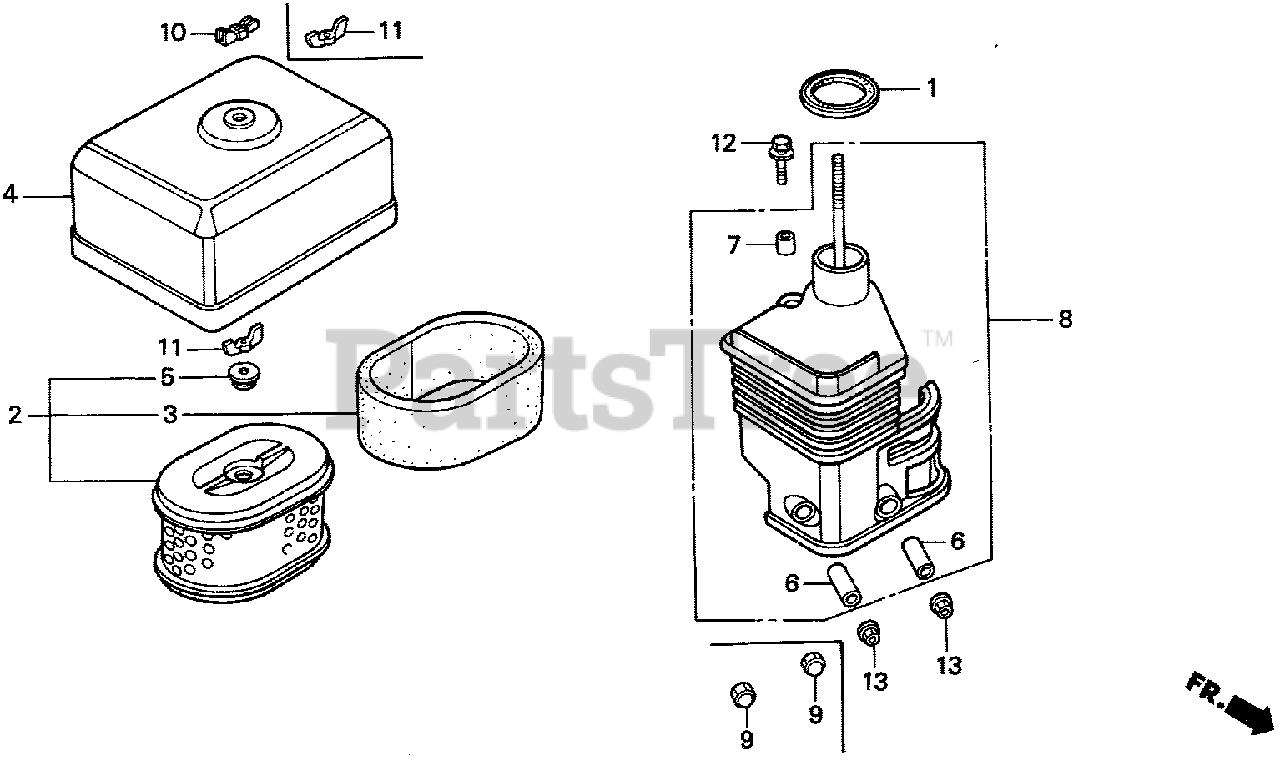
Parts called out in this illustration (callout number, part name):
1	GASKET, ELBOW
2	ELEMENT, AIR CLEANER (DUAL)
3	FILTER (OUTER)
3	FILTER (OUTER) (NOT AVAILABLE)
4	COVER, AIR CLEANER (DUAL)
5	GROMMET, AIR CLEANER
6	COLLAR, AIR CLEANER
7	COLLAR B, AIR CLEANER
8	ELBOW, AIR CLEANER
9	NUT, CAP (6MM)
10	WINGNUT, AIR CLEANER COVER
10	WINGNUT (6MM)
11	WINGNUT, TOOL BOX SETTING
12	BOLT-WASHER (6X20)
12	BOLT, FLANGE (6X20)
13	NUT, FLANGE (6MM)
